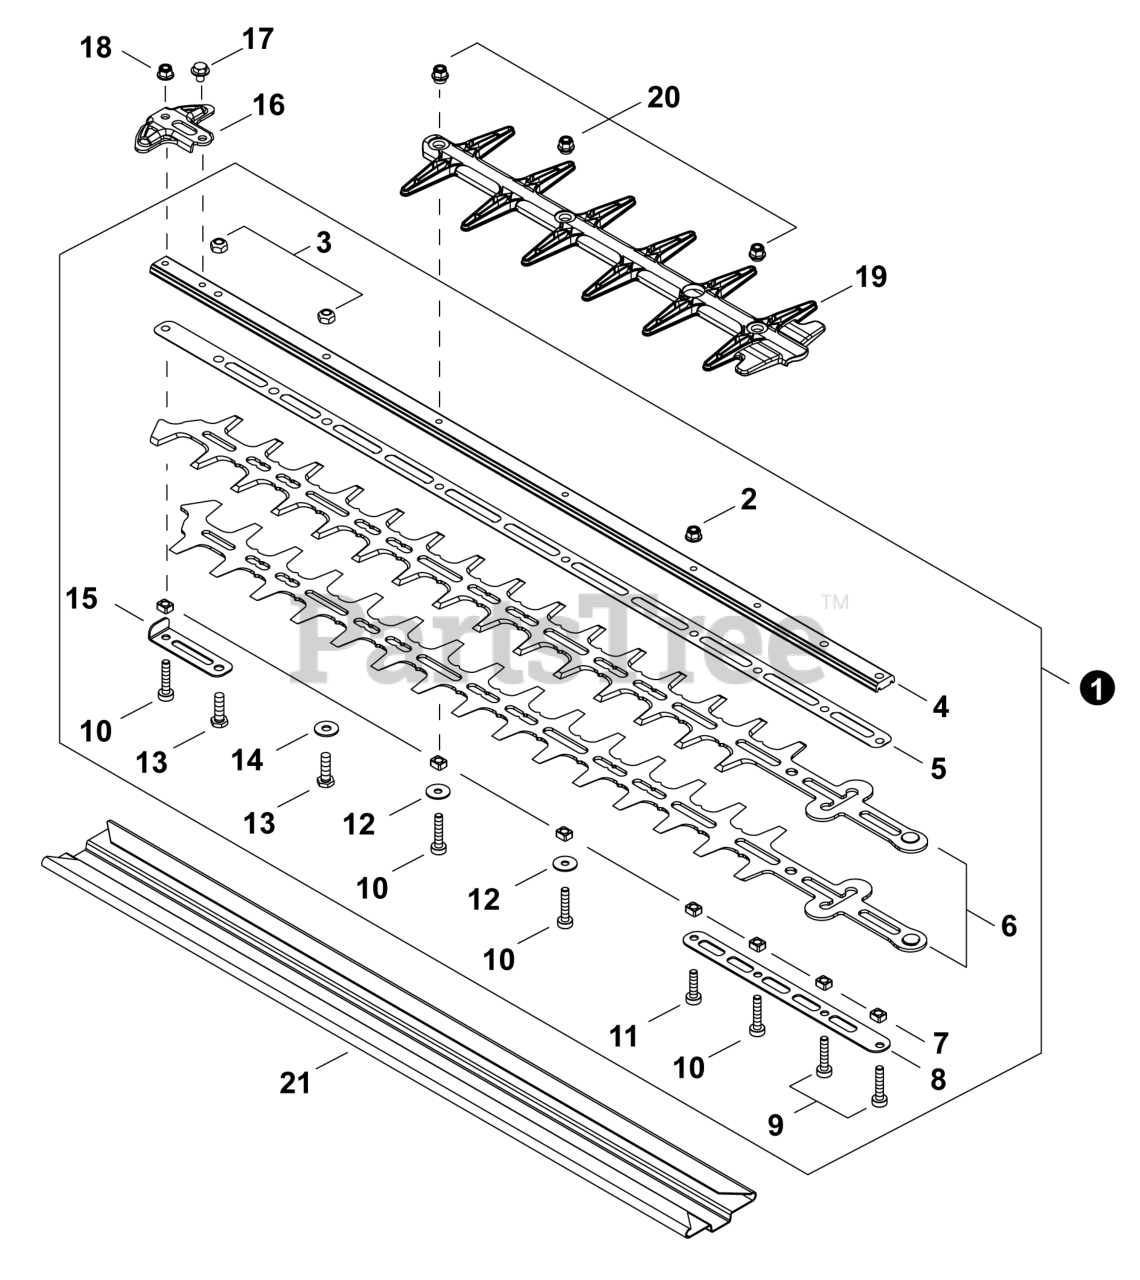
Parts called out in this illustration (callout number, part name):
1	CUTTER ASSY, 24"
2	NUT, FLANGE M5
4	SUPPORT, CUTTER 24"
5	PLATE, CUTTER 24"
6	CUTTER 24"
7	GUIDE, BLADE
8	PLATE, CUTTER
9	BOLT, TORX 5x25
10	BOLT, TORX 5x25
11	BOLT, TORX 5x20
13	BOLT M6x20
14	WASHER M6
15	PLATE, EYE
16	GUARD, TIP
18	NUT, FLANGE M5
19	GUARD, CUTTER BLADE
20	NUT, FLANGE M5
21	SCABBARD
